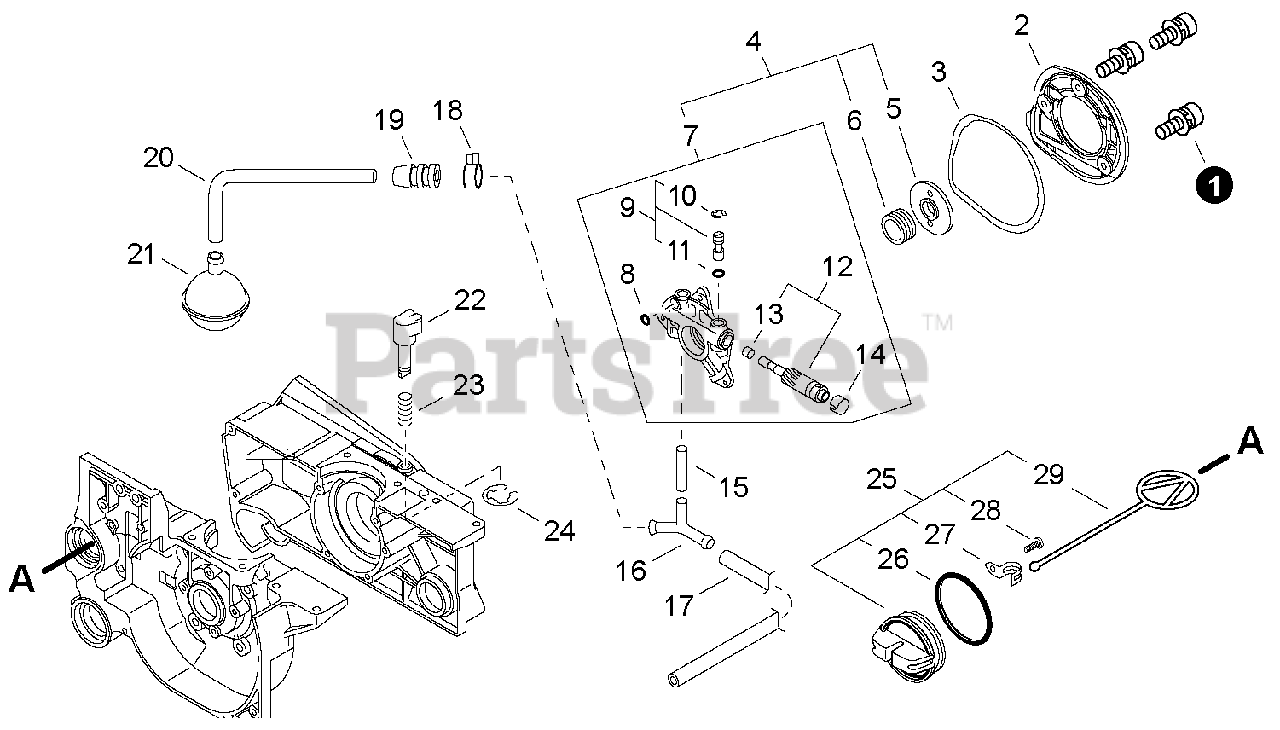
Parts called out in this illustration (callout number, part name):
1	BOLT 4×12
2	COVER, OILER
3	GASKET, OILER COVER
4	AUTO-OILER KIT
5	WASHER 12
6	GEAR, WORM
7	AUTO-OILER ASSY
8	O-RING 3
9	PIN ASSY, CONTROL
12	PLUNGER KIT
14	CAP, PLUNGER
15	PIPE, OIL 3×6×20
16	CONNECTOR, PIPE
17	PIPE, FUEL 3×6×200
18	CLIP Ø6.5 MM
20	PIPE, OIL
21	FILTER, OIL
24	E-RING 3
25	CAP ASSY, OIL
27	RETAINER, CONNECTOR
28	SCREW, TAPPING 3×8
29	CONNECTOR, CAP L= 60 MM
